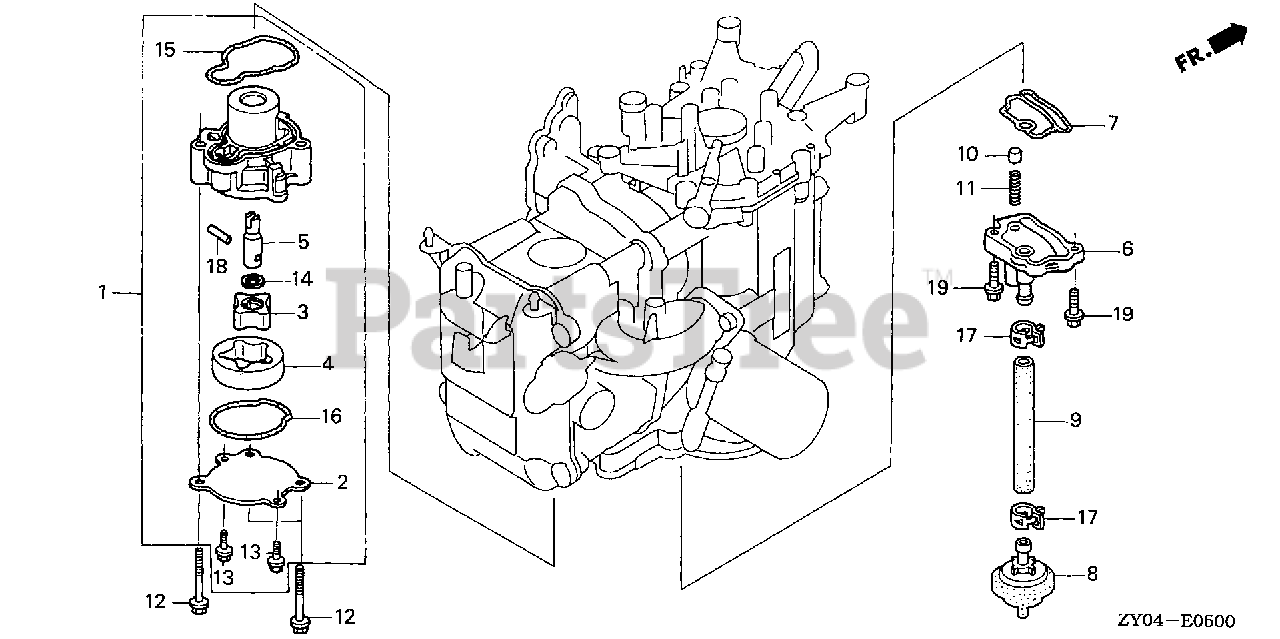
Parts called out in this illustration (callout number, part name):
1	PUMP ASSY., OIL
2	COVER, OIL PUMP
3	ROTOR (INNER)
4	ROTOR (OUTER)
5	SHAFT, OIL PUMP
6	FLANGE, OIL STRAINER
7	O-RING, OIL STRAINER FLANGE
8	STRAINER, OIL
10	VALVE, CHECK
11	SPRING, CHECK VALVE
12	BOLT, FLANGE (6X35)
13	BOLT, FLANGE (5X12) (CT200)
14	WASHER, THRUST (11MM)
15	O-RING, OIL PUMP
16	O-RING, PUMP COVER
17	CLAMP, TUBE (D17)
18	ROLLER (4X15.8)
19	BOLT, FLANGE (6X22)
